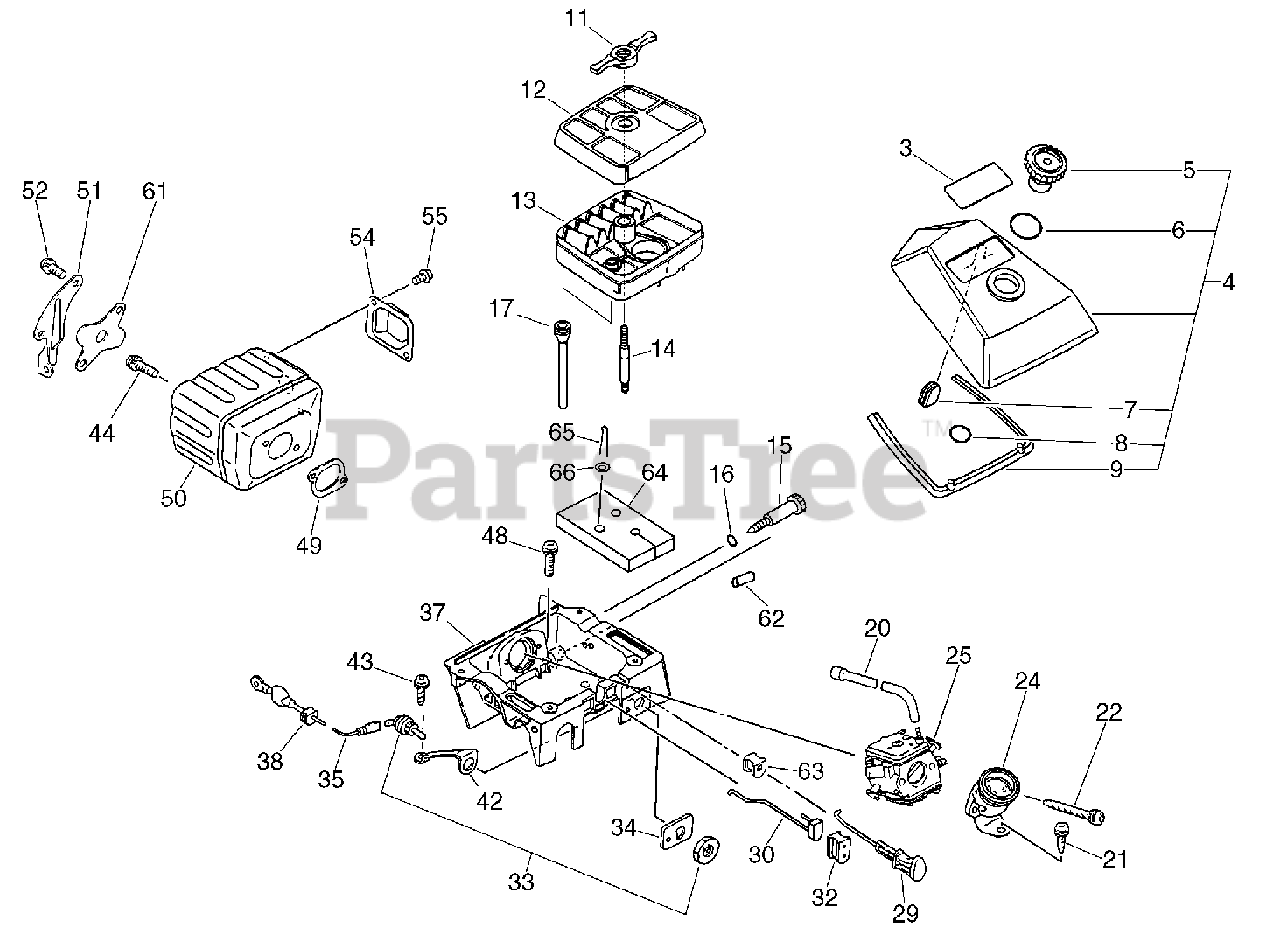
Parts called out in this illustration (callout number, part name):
3	LABEL - MODEL
4	COVER ASSY, AIR FILTER
5	THUMBSCREW
6	O-RING -21
8	O-RING P-11
9	GASKET, AIR FILTER
11	HOLDER
12	FILTER, AIR
13	FILTER, AIR
14	BOLT 5
15	SCREW, IDLE ADJUST - ORANGE
16	O-RING 7
20	PIPE, IMPULSE
21	SCREW 5×14
22	SCREW 5×53
24	ADAPTOR, INTAKE
25	CARBURETOR
29	ROD, CHOKE
30	ROD, THROTTLE
32	GROMMET, THROTTLE ROD
33	SWITCH, ON-OFF
34	LABEL, STOP
35	LEAD
37	CASE, CARBURETOR
42	PLATE, GROUND
43	SCREW 4×10
44	BOLT 5×20
48	BOLT 5×20
49	GASKET, EXHAUST
50	MUFFLER
51	BRACKET, MUFFLER
52	BOLT 5×14
54	OUTLET, EXHAUST
55	BOLT 4×10
61	COVER, MUFFLER
63	GROMMET
64	GASKET, CARBURETOR CASE
65	PIN, COTTER 3×18
